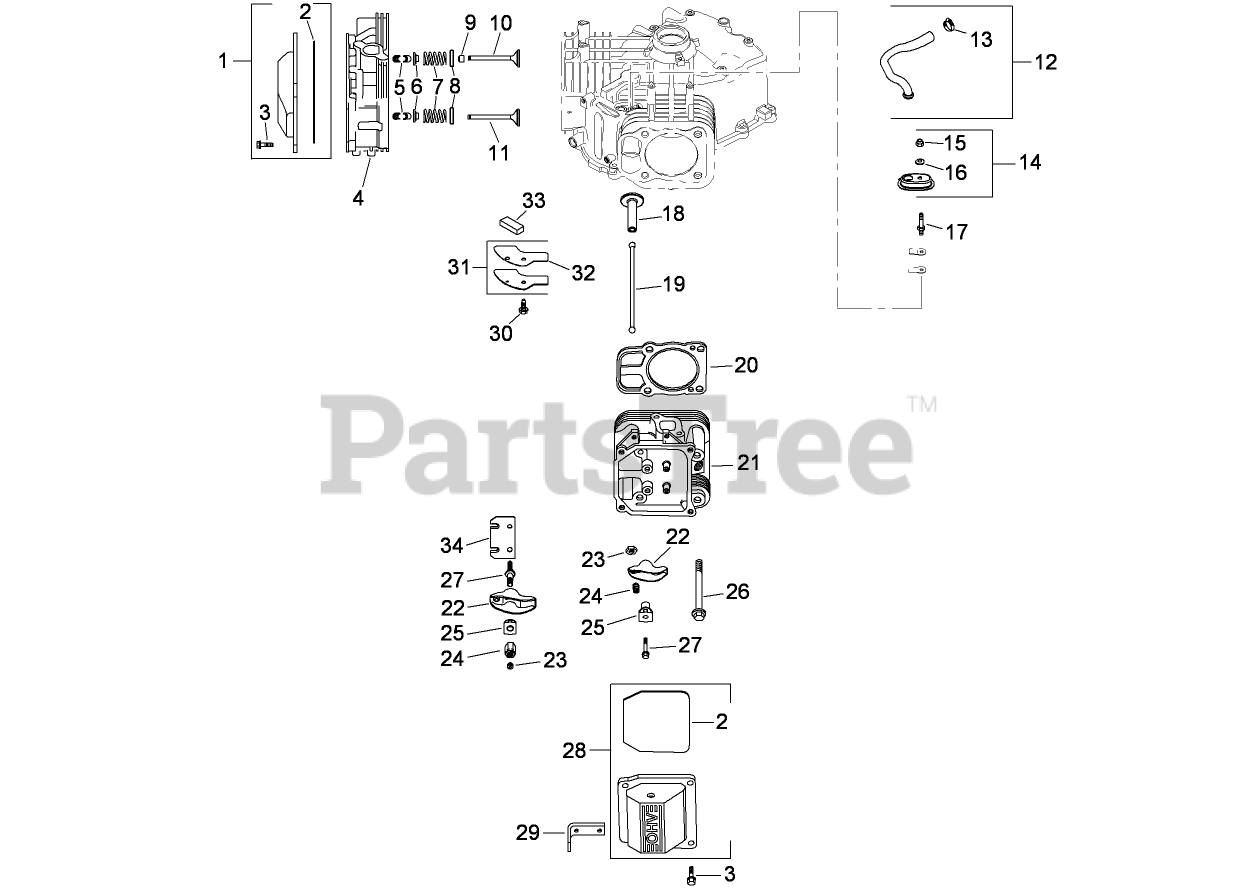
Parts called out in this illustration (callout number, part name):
1	PLAIN ROCKER COVER KIT
2	O-RING
3	SCREW-FLANGE (M6X1.0X30)
4	CYLINDER HEAD No.1 ASM (INCLUDES 26 [QTY 4] and 20)
5	RETAINER KIT
6	CAP-SPRING, VALVE
7	SPRING-VALVE
8	RETAINER-SPRING
9	SEAL-STEM, VALVE
10	VALVE-INTAKE (STD)
11	VALVE-EXHAUST (STD)
12	BREATHER HOSE KIT
13	CLAMP-HOSE, SPRING (1/2)
14	BREATHER HOUSING KIT (INCLUDES 15-16)
15	NUT-LOCK (M5X.8)
16	WASHER-SEALING
17	STUD-COVER, BREATHER
18	Tappet
19	ROD-PUSH
20	CYLINDER HEAD GASKET KIT
21	CYLINDER No.2 HEAD ASM
22	ARM-ROCKER
23	NUT (M10X0.75 )
24	SCREW-SET
25	PIVOT-ARM, ROCKER
26	SCREW-FLANGE (M10X1.5X90)
27	STUD-ROCKER
28	BREATHER VALVE COVER KIT
29	STRAP-LIFTING
30	SCREW-FLANGE, THREAD FORMING (M6X1.0X16)
31	BREATHER COVER KIT
32	GASKET-COVER, BREATHER
33	FILTER-BREATHER
34	PLATE-GUIDE
